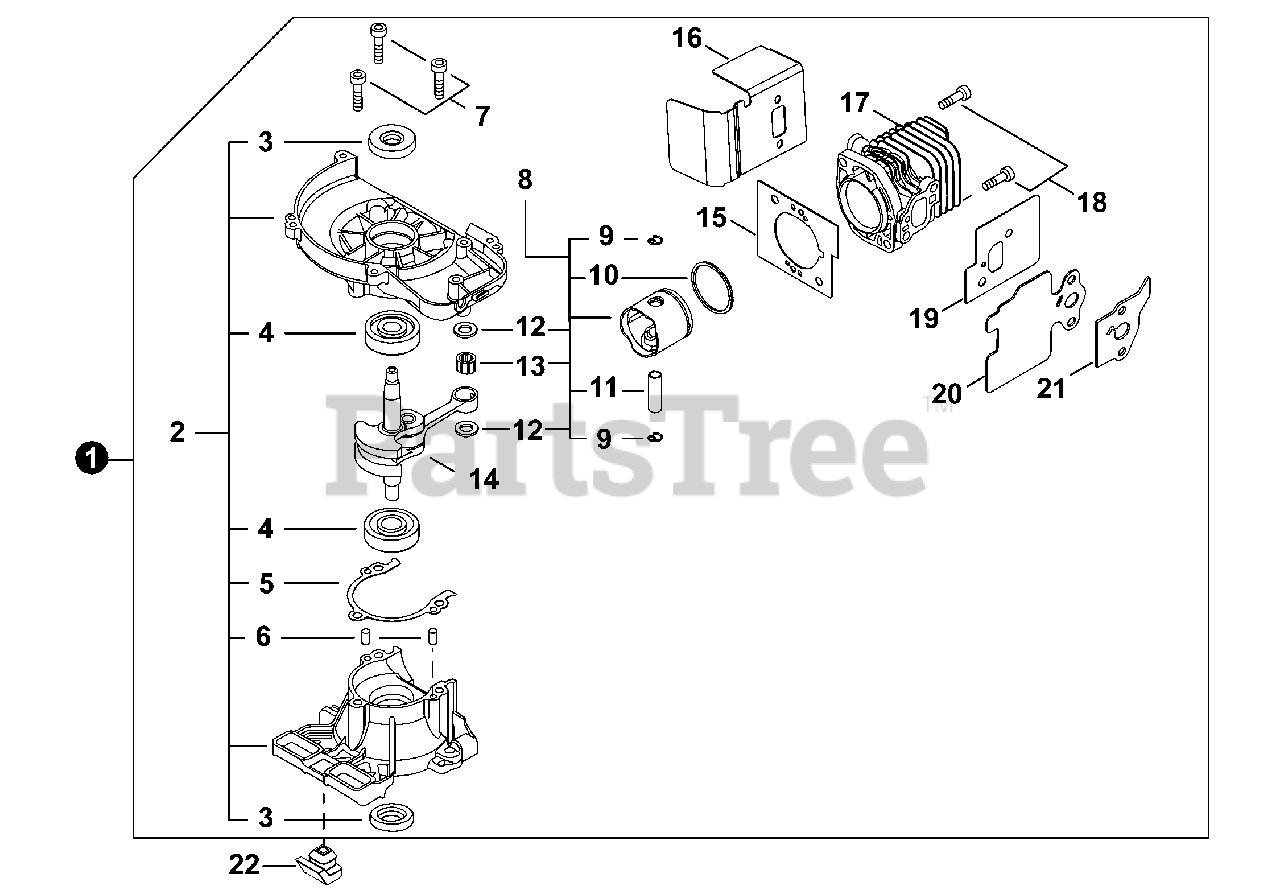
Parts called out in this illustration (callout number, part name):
1	SHORT BLOCK
2	CRANKCASE KIT
3	SEAL, OIL
4	BEARING, BALL
5	GASKET, CRANKCASE
6	PIN, LOCATING 4×8
7	BOLT 5×28
8	PISTON KIT
9	RING, SNAP
10	RING, PISTON
11	PIN, PISTON 8
12	WASHER, THRUST
13	BEARING, NEEDLE
14	CRANKSHAFT ASSY
15	GASKET, CYLINDER
16	HEAT SHIELD, EXHAUST
17	CYLINDER
19	GASKET, INTAKE
20	GASKET, INTAKE
21	GASKET, INTAKE
22	CUSHION
